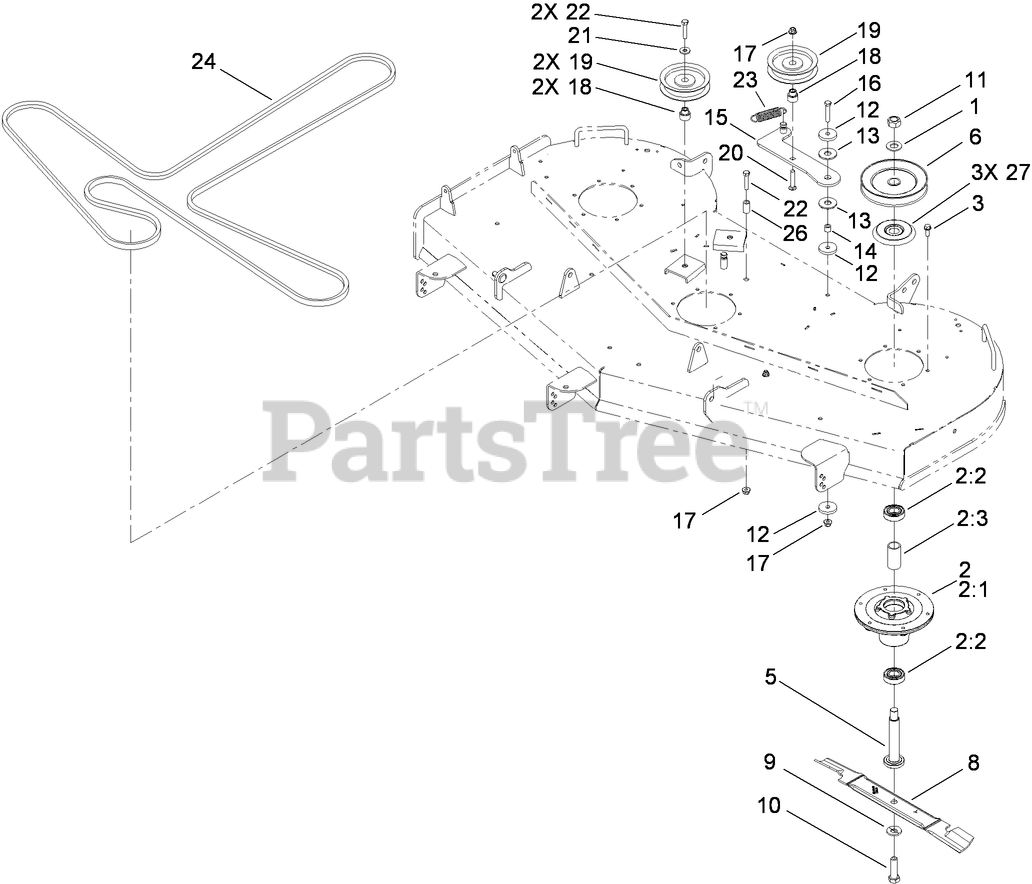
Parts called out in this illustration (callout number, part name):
1	WASHER
2:3	SPACER-BEARING
3	SCREW-TAPTITE
5	SHAFT-SPINDLE
6	PULLEY
8	BLADE-HI FLOW, 20.5 INCH
10	SCREW-BLADE
11	NUT-HEX
12	WASHER-PLAIN
13	WASHER-FRICTION, COMPOSITE
14	BUSHING-LEVER, LIFT
15	ARM-IDLER
16	SCREW-HH
17	NUT-HF, NI
18	BUSHING-IDLER
20	SCREW-CARR
21	WASHER-HARDENED
22	SCREW-HH
23	SPRING-EXTENSION
26	SPACER
27	SHIELD-BEARING
